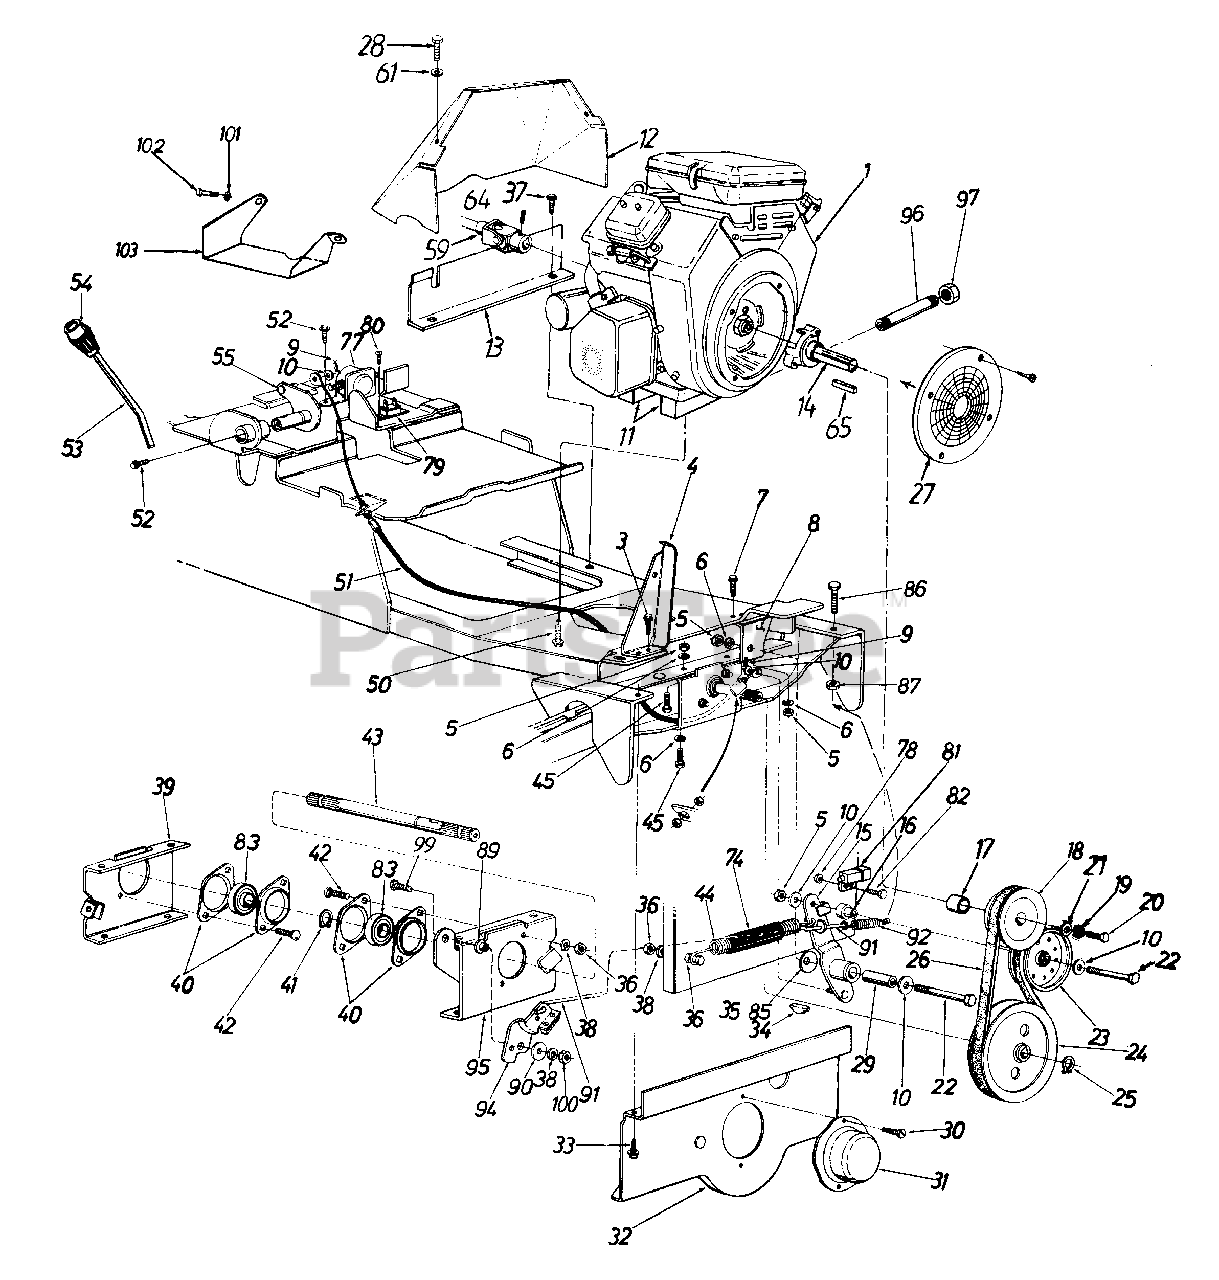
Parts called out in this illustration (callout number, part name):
1	Engine
3	Hex Wash. Hd. Self-Tap Scr. 1/4-20 x .75" Lg.
6	L-Wash. 3/8" I.D.
7	Hex Wash. Hd. Self-Tap Scr. 5/16-18 x .75" Lg.
10	Fl-Wash. .38" I.D. x 1.25" O.D. x .100" Thk.
11	Engine spacer Bar
14	Crankshaft Ext.
17	Pulley Spacer
18	Engine PTO-Pulley
19	L-Wash. 3/8" I.D.
20	Hex Bolt 3/8-24 x .88" Lg.
21	Fl-Wash. 3/8" I.D. x 1.37" O.D.
22	Hex Bolt 3/8-16 x 2.50:" Lg.
23	Flat Idler Pulley
24	1/2" V-Pulley 7.00" O.D. (PTO)
25	Snap Ring
26	"V"-Belt (PTO)
27	Engine Screen
28	Hex Bolt M6-1.0 x 10 MM Lg.
29	Spacer .375" I.D. x .62" O.D. x 1.830" Lg.
30	Hex "B" Tap Scr. #10 x .50" Lg.
34	#91 Hi-Pro Key
35	Hex Bolt 5/16-18 x 1.25" Lg.
36	Hex Nut 5/16-18 Thd.
37	Hex Wash. Hd. Tap Scr. 5/16-18 x .5" Lg.
38	L-Wash. 5/16" I.D.
40	1.00" Dia. Brg. w/Flangette
41	Snap Ring
42	Carr. Bolt 5/16-18 x .75" Lg.
43	Spline Shaft
44	Extension Spring (PTO Clutch)
45	Hex Scr. 3/8-16 x 1.00" Lg.
50	Hex L-Wash. TT-Tap Scr. 3/8-16 Thd.
51	PTO Control Cable
53	PTO Handle
54	Shift Knob
55	PTO Actuator Lever Ass'y.
59	Universal Drive Shaft Comp.
61	Fl-Wash. .281" I.D. x .5" O.D.
64	Set Scr. 5/16-18 x .38" Lg.
65	Sq. Key 1/4" x 2.00" Lg.
74	Spring Cover Tubing (PTO Clutch)
77	Solenoid
78	Hex Bolt 1/4-20 x 1/2" Lg.
79	Circuit Breaker
80	Truss Mach. Scr. #10 x .50" Lg.
81	Safety Switch (PTO)
82	L-Wash. 1/4" I.D.
83	Ball Bearing
85	Bell-Wash. .39" I.D. x 1.13"
86	Hex Bolt 3/8-16 x 1.5" Lg.
87	Hex Cent. L-Nut 3/8-16 Thd.
89	Shoulder spacer
90	Fl-Wash. .38" I.D. x 1.25" O.D.
91	PTO Brake Rod
92	Extension Spring 2.15" Lg.
95	PTO Brg. Retainer Brkt. Ass'y.
96	Pipe Nipple 3/8" x 5" Lg.
97	Oil Drain Cap
99	Hex Bolt 5/16-24 x .75" Lg.
100	Hex Nut 5/16-24 Thd.
101	L-Wash. 7/16" I.D.
102	Hex Bolt 7/16-14 x .75" Lg.
103	Heat Shield
